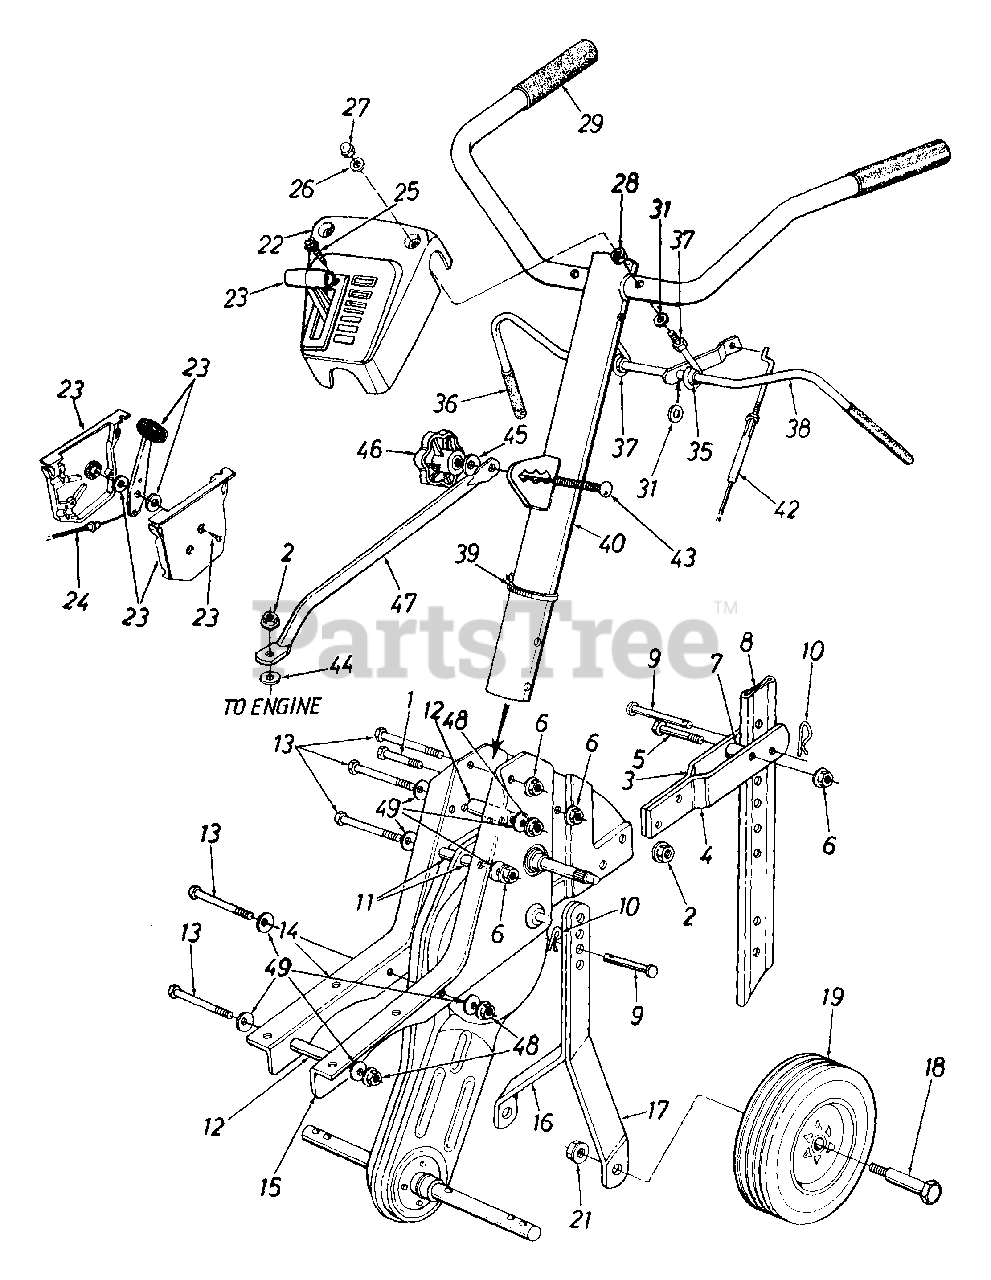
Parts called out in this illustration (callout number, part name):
1	Hex Bolt 5/16-18 x 1.25" Lg.
2	Hex Flange L-Nut 5/16-18 Thd. (Gr. 5)
5	Hex Bolt 5/16-18 x 1.5" Lg.
6	Hex Flange L-Nut 5/16-18 Thd. (Gr. 5)
7	Spacer .32" I.D. x .75" O.D.
9	Clevis Pin .375" I.D. x 1.75" Lg.
10	Internal Cotter Pin
11	Spacer .326" I.D. x .47" O.D.
12	Spacer .322" I.D. x .44" O.D.
13	Hex Bolt 5/16-18 x 2.75" Lg.
17	Wheel Hanger Brkt.- L.H.
18	Shld. Bolt .498" Dia.
19	Wheel Ass'y. 8" x 1.75"
21	Hex Flange L-Nut 3/8-16 Thd. (Gr. 5)
22	Handle Cover
23	Throttle Control Box Ass'y.
24	Throttle Control Wire 30.5" Lg.
25	Truss Mach. AB-Tap Scr. #10 x .5" Lg.
26	Fl-Wash. .266" I.D. x .625" O.D.
27	Hex L-Stop Nut 1/4-28 Thd.
28	Hex Nut 1/4-28 Thd.
29	Grip - Handle
31	Fl-Wash. .385" I.D. x .62" O.D.
35	Plastic Bushing .38" I.D.
36	Grip - Clutch
37	Clutch Handle Eye Bolt
43	Carr. Bolt 5/16-18 x 1" Lg. (Special)
44	Fl-Wash. .344" I.D. x 1.12" O.D.
45	Bell-Wash. .345" I.D. x .88" O.D.
46	Hand Knob
49	Bell-Wash. .345" I.D. x .88" O.D.
